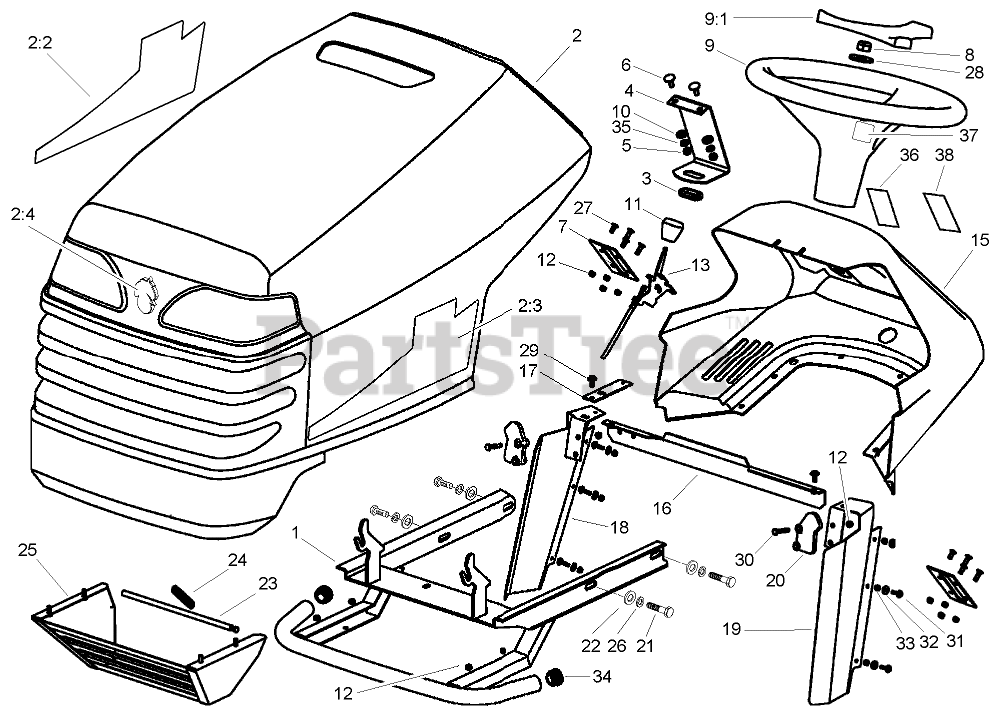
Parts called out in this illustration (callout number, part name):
1	SUPPORT-BUMPER
2	HOOD ASM
2:2	DECAL-HOOD, RH
2:3	DECAL-HOOD, LH
2:4	EMBLEM
3	BUSHING
4	HOLDER-TANK, FUEL
5	NUT-LOCK
8	NUT-LOCK
9	WHEEL-STEERING
9:1	COVER-WHEEL, STEERING
10	WASHER-PLAIN
12	NUT-LOCK
13	CABLE-THROTTLE and CHOKE
15	PANEL-DASH
17	BRACKET
18	PANEL-RIGHT
19	PANEL-LEFT
20	LATCH-HOOD
21	SCREW-HH
22	WASHER-PLAIN
23	BAR-SAFETY
24	SPRING-HOOD
25	GUARD-MUFFLER
26	WASHER-LOCK, SPRING
28	Washer
32	WASHER
33	NUT-HEX
34	PLUG-END, TUBE
35	WASHER-LOCK, SPRING
36	DECAL-DASH THROTTLE and IGNITION
37	DECAL
38	DECAL-PTO
